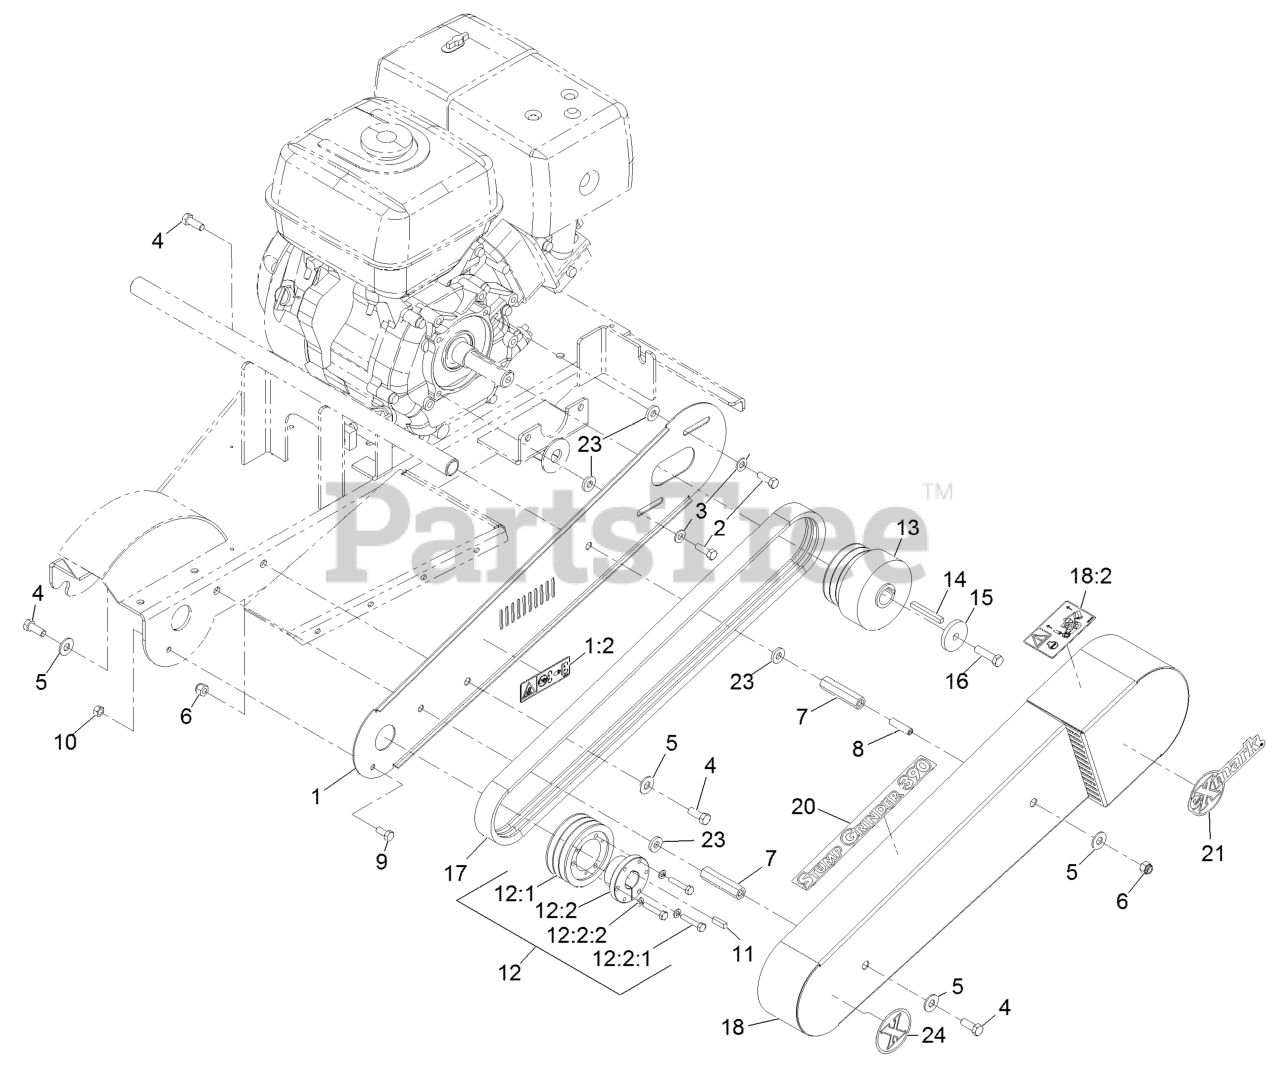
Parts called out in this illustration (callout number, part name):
1	PLATE-GUARD
1:2	DECAL-WARNING
2	SCREW-HH
3	WASHER-FLAT
4	SCREW-HH
5	WASHER-FLAT
6	NUT-LOCK, NI
7	SPACER-GUARD
8	SCREW-SET, HSH
9	SCREW-HH
10	NUT-HEX
11	KEY-SQUARE
12	SHEAVE ASM
12:2	BUSHING
12:2:1	SCREW-HH
12:2:2	WASHER-LOCK
14	KEY-SQUARE
15	WASHER-PLAIN
16	SCREW-HH
17	BELT-3V
18	BELT GUARD ASM
18:2	DECAL-CAUTION
20	DECAL-STUMP GRINDER 390
24	DECAL-EXMARK X-LOGO 2.64
